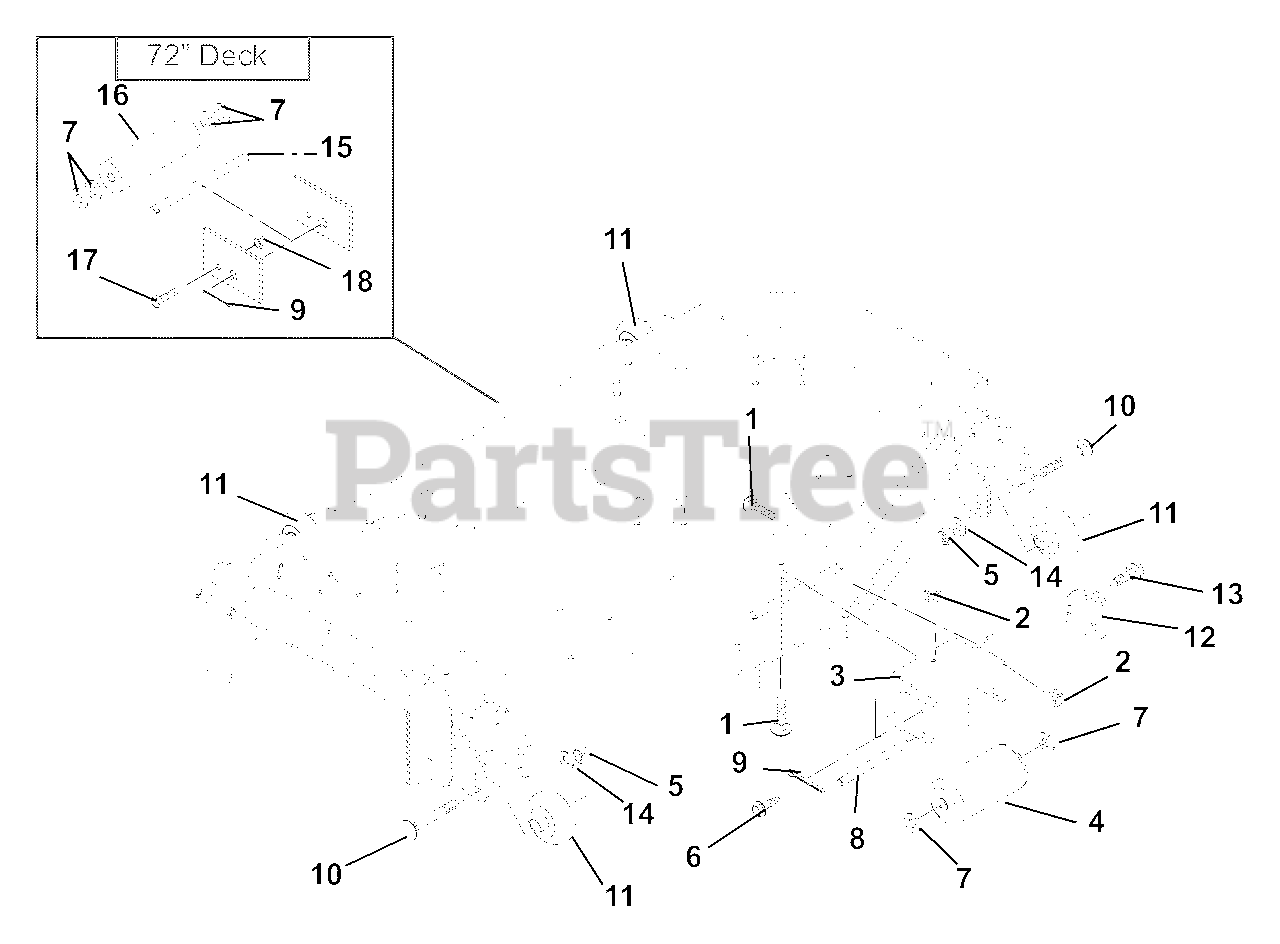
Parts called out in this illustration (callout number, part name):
1	Bolt-Round Head Square Neck .38-16 x 1.00 Grade 5
2	Nut-Locking-Top-Flange .38-16
3	Bracket- Anti-Scalp Roller
5	Nut-Locking-Nylon .50-13
6	Screw-Tapping .25-20 x .75 Hex Washer Head
7	Washer-Flat-Steel .656 x 1.31 x .095 (073, 075, 318, 319)
7	Washer-Flat-Steel .656 x 1.31 x .095 (074, 076)
9	Pin-Cotter .25 x 2.00 (073, 075, 318, 319)
9	Pin-Cotter .25 x 2.00 (074, 076)
10	Bolt-Round Head Square Neck .50-13 x 5.00 Grade 2
11	Wheel, 3 x 5
12	Anti-Scalp Washer
13	Screw-Tapping .25-20 x .62 Hex Washer Head
14	Washer-Flat-Steel .531 x 1.06 x .095
15	Shaft, Center Roller (074, 076)
16	Roller, Gage (074, 076)
17	Bolt-Hex .25-20 x .75 Grade 5 (074, 076)
18	Nut-Locking-Center .25-20 (074, 076)
